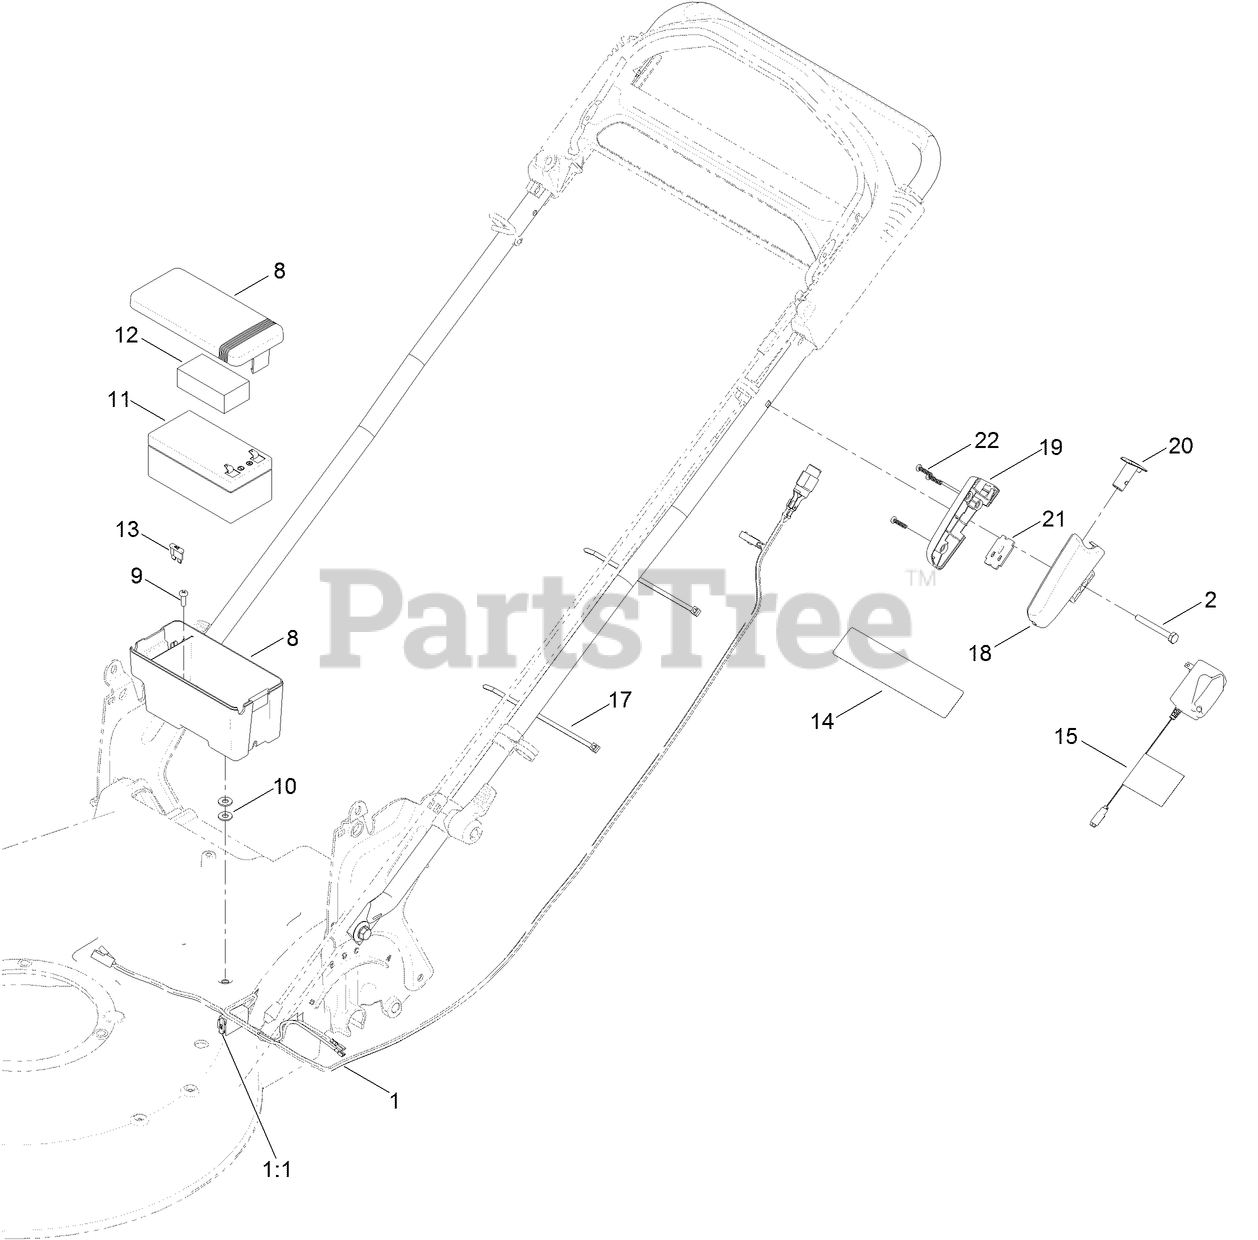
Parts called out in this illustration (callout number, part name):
1	HARNESS-WIRE
1:1	FUSE-40 AMP
2	SCREW-HH
8	BATTERY BOX ASM
10	WASHER-FLAT
11	BATTERY-WET
12	FOAM-BATTERY, TOP
13	FUSE-40 AMP
14	DECAL-WARNING
15	CHARGER-BATTERY
17	TIE-CABLE
18	HOUSING-SWITCH, LH
19	HOUSING-SWITCH, RH
20	BUTTON-SWITCH
21	SWITCH-PUSH BUTTON
22	SCREW-PPH
